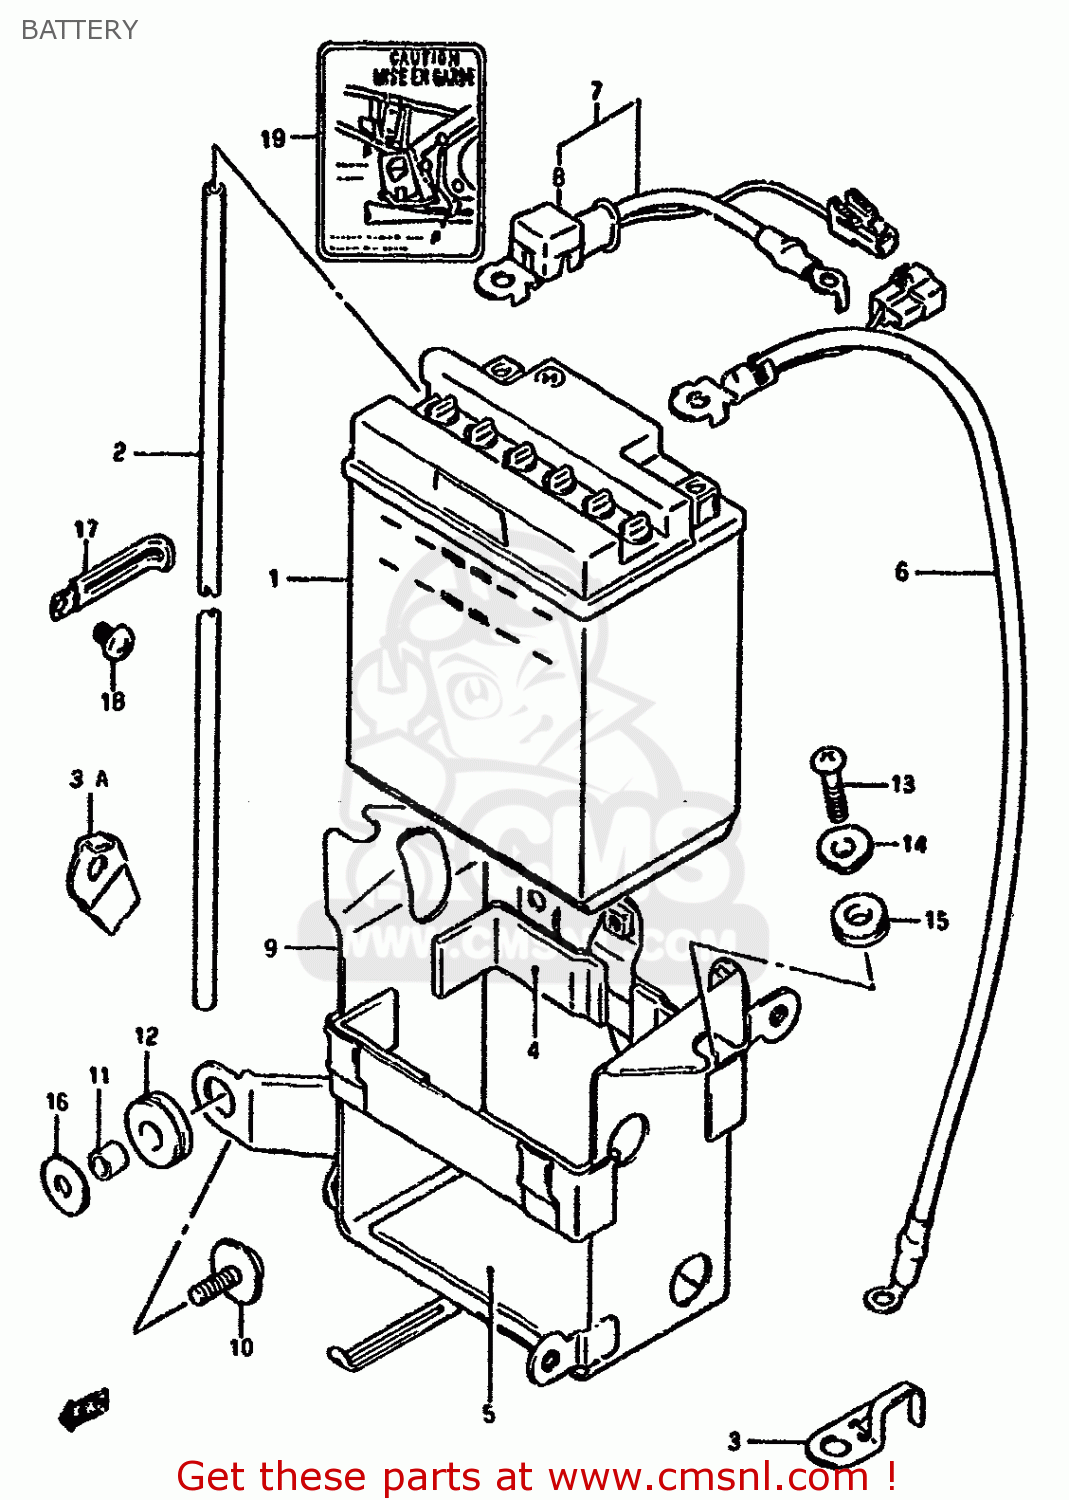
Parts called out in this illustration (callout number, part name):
1	BATTERY(YB14L-B2,12V14.7AH)
2	HOSE,BATTERY EXHAUST
3	CLAMP,BATTERY EXHAUST HOSE
3A	CLAMP,BATTERY EXHAUST HOSE
4	PROTECTOR,20X9
5	PROTECTOR(170X95X3.0)
6	WIRE,BATTERY MINUS LEAD
7	WIRE,BATTERY PLUS
8	CAP,BATTERY PLUS
9	HOLDER,BATTERY
10	SCREW
11	SPACER
12	CUSHION
13	SCREW, CENTER
14	WASHER
15	CUSHION
16	WASHER(6,5X22X1.6)
17	CLAMP
18	SCREW
19	PLATE,BATTERY CAUTION
